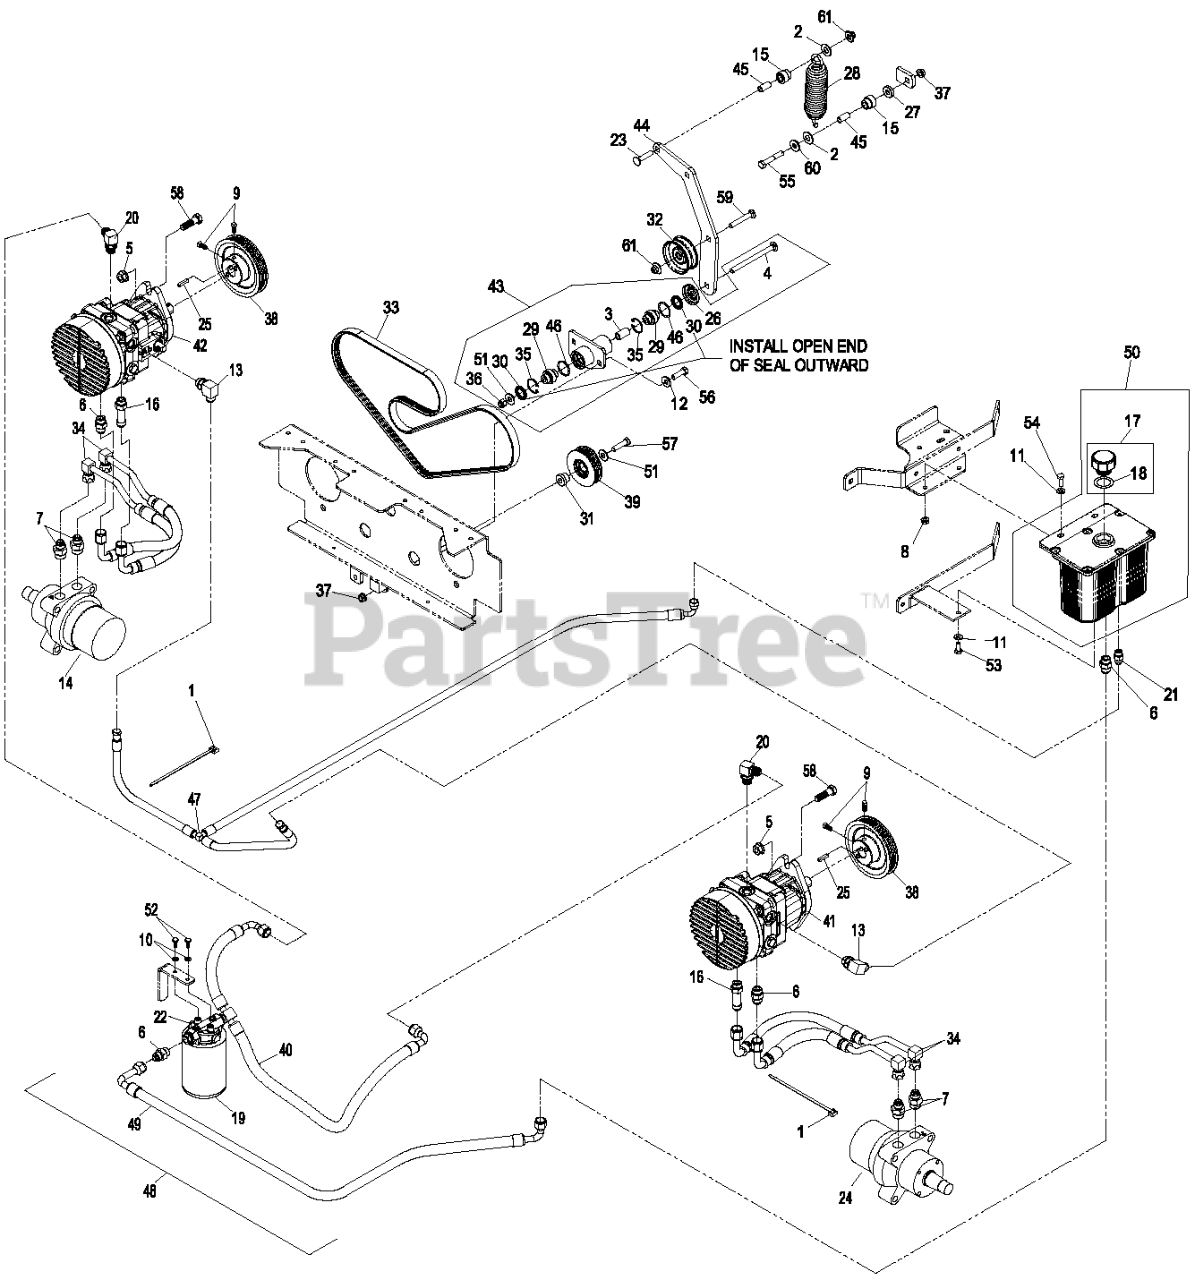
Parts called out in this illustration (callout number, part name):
1	TIE-PLASTIC
2	WASHER-TEFLON
4	BOLT CARR 3/8-16X5
5	NUT-HHF
6	FITTING-STRAIGHT
7	FITTING-STRAIGHT
9	SCREW-SET
10	WASHER-LOCK
11	WASHER-PLAIN
12	WASHER-BELLEVILLE
13	FITTING-ELBOW, 90 DEG
14	HYD MOTOR ASM (CW)
15	BUSHING,PLASTIC
16	ADAPTER-STR, LONG
17	KIT,HYD RES CAP W/GASKET
18	GASKET-CAP
19	FILTER,XP HYD 25 MICRON
20	FITTING-90 DEG
21	FITTING-STRAIGHT
22	HEAD-FILTER
23	SCREW-CARR
24	HYD MOTOR ASM (CCW)
26	GUARD-TOP
27	SPACER-BRACKET, GUIDE
29	BEARING-SPHERICAL
30	SEAL-LIP, SINGLE
31	SPACER,LOWER FRAME IDLER
32	IDLER,PUMP
33	BELT, 5K 68.8
34	HYD HOSE ASM
35	RING-SNAP
36	NUT-LOCK, NI
37	NUT-HHF, WHIZ
38	SHEAVE,5K 5.0" PD POLY-V
39	ASM,LOWER FRAME IDLER
40	ASM, HOSE-PUMP INLET
41	PUMP, LH
42	PUMP, RH
43	KIT,PUMP IDLER
44	ARM,PUMP IDLER
47	ASM,CASE DRAIN HOSE
48	Asm, Charge Hose
49	ASM, HOSE-FILTER INLET
50	HYDRAULIC TANK ASM
51	WASHER-FLAT
52	SCREW-HH
53	SCREW-HH
54	SCREW-HH
55	SCREW-HH
56	SCREW-HH
57	SCREW-HH
58	SCREW-HH
59	SCREW-CARR
60	WASHER
61	Nut-Nyloc 3/8-16 Flg
